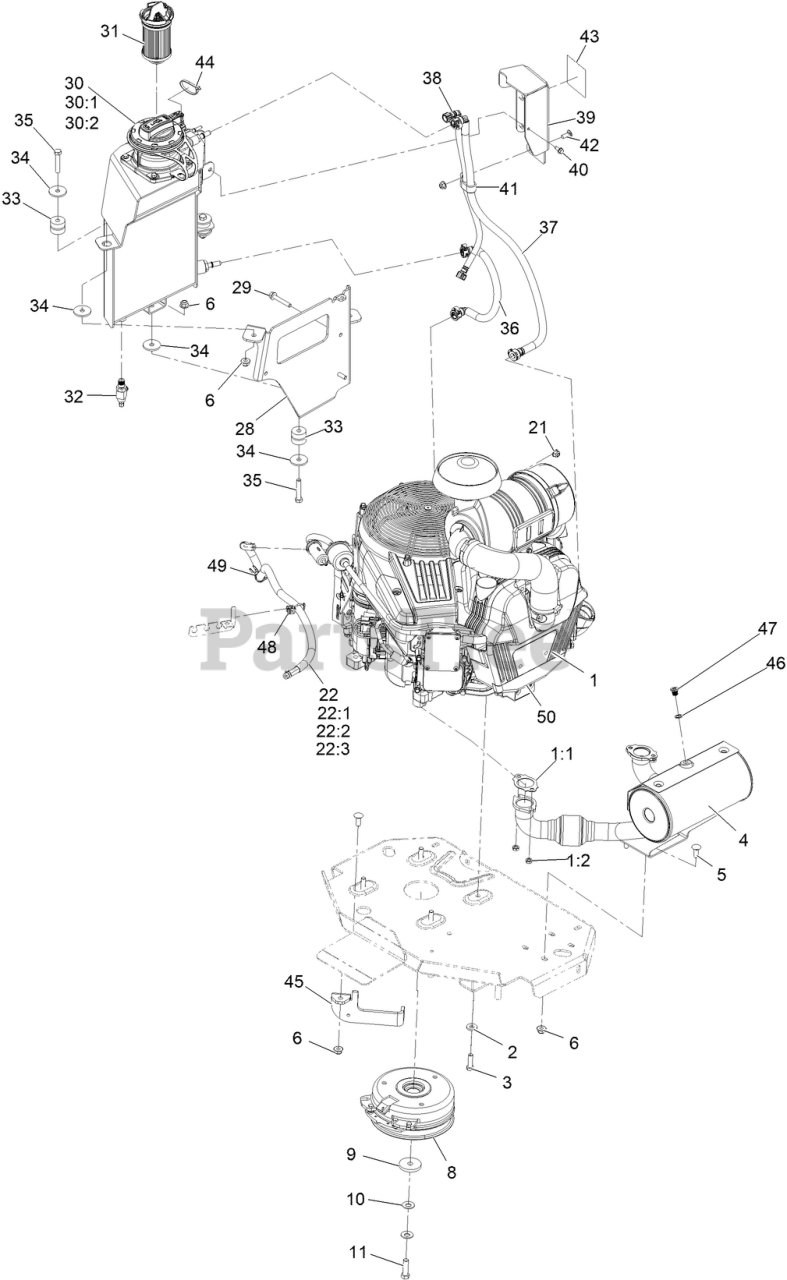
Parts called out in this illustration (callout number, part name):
1	Engine Vanguard EFI
1:1	GASKET-EXHAUST
1:2	NUT-HEX
2	WASHER-BELLEVILLE
3	SCREW-HH
4	MUFFLER
5	SCREW-CARR
6	NUT-HF, NI
8	CLUTCH KIT
9	WASHER-CLUTCH
10	WASHER-SPRING
11	SCREW-HH 7/16-20 X 1 1/2 W/LOCTITE
21	NUT-HF, NI
22	FUEL LINE ASM
22:1	HOSE-FUEL
22:2	SLEEVE, THERMAL
22:3	CLAMP-HOSE
28	Mount-Tank, Oil
29	SCREW-HHF
30	RESERVOIR-OIL
30:1	OIL DIPSTICK ASM
30:2	OIL TANK CAP ASM
31	FILTER-OIL
32	VALVE-OIL DRAIN
33	ISOLATOR-TANK
35	SCREW-HH
36	HOSE-SUPPLY
37	HOSE-SCAVENGE
38	HOSE-VENT
39	GUARD-HOSE
40	SCREW-HWH
42	SCREW-CARR
43	DECAL-OIL GUARD
44	TIE-CABLE
45	Bracket-Clutch Anchor
46	Washer-Copper
47	Plug-HSH
48	Clip-Edge
49	Clip-Edge W/Tie, Perpendicular
50	Shield-Heat, 993
